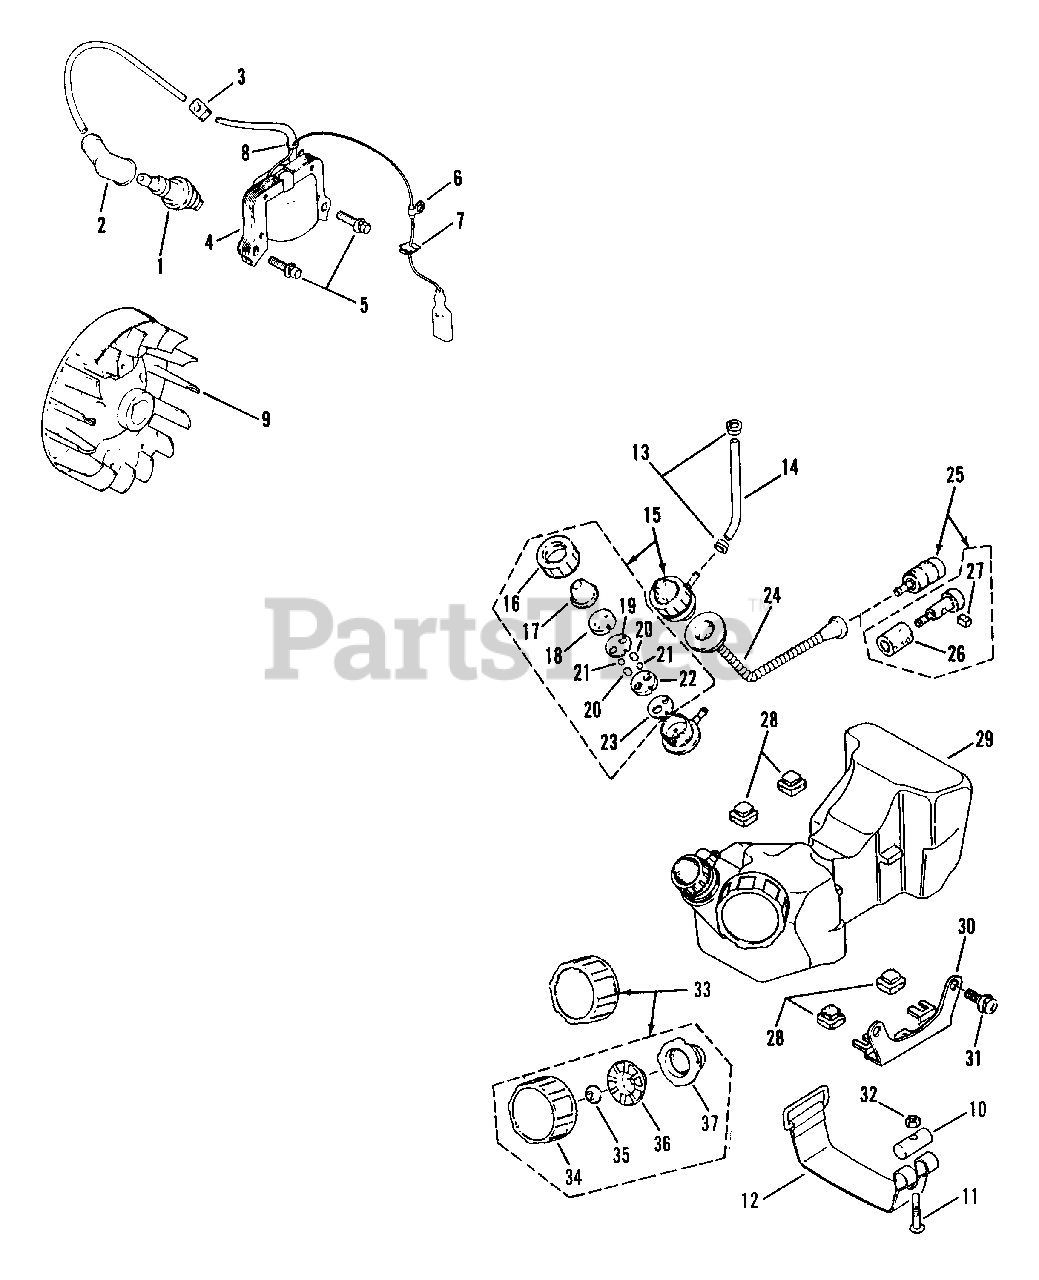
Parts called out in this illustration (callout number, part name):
1	SPARK PLUG (NGK:BM-6A)
2	BOOT, Spark Plug
3	BUSHING, Dust Seal
4	COIL, Ignition
7	BUSHING, Dust Seal
8	BAND
9	FLYWHEEL
10	BAR, Band Support
12	BAND, Tank
13	CLIP, Fuel Tube
14	TUBE, Fuel
15	PRIMER PUMP ASSM'Y.
16	CAP, Pump
17	CAP, Rubber
18	SEAT, Valve B
22	SEAT, Valve A
24	HOSE, Fuel
25	FILTER ASSM'Y., Fuel
29	TANK ASQM'Y., Fuel
30	HANGER, Tank
31	SCREW, Hanger
33	CAP ASSM'Y., Fuel
34	CAP, Fuel
37	GASKET
